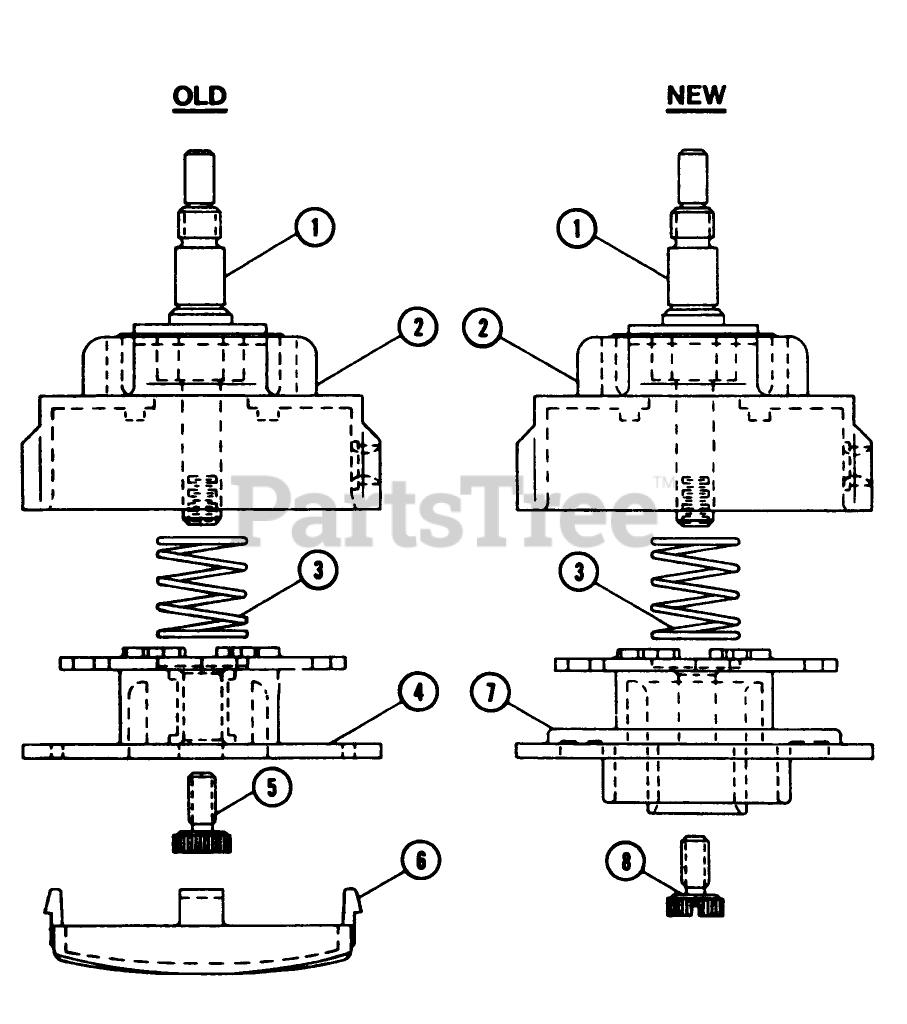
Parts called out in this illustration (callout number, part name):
1	Drive Shaft
2	Spool Housing w/Eyelet
3	Actuator Spring
4	Cartridge Spool
5	Thumb Screw
6	Bump Knob
7	Cartridge Spool
8	Thumb Screw
